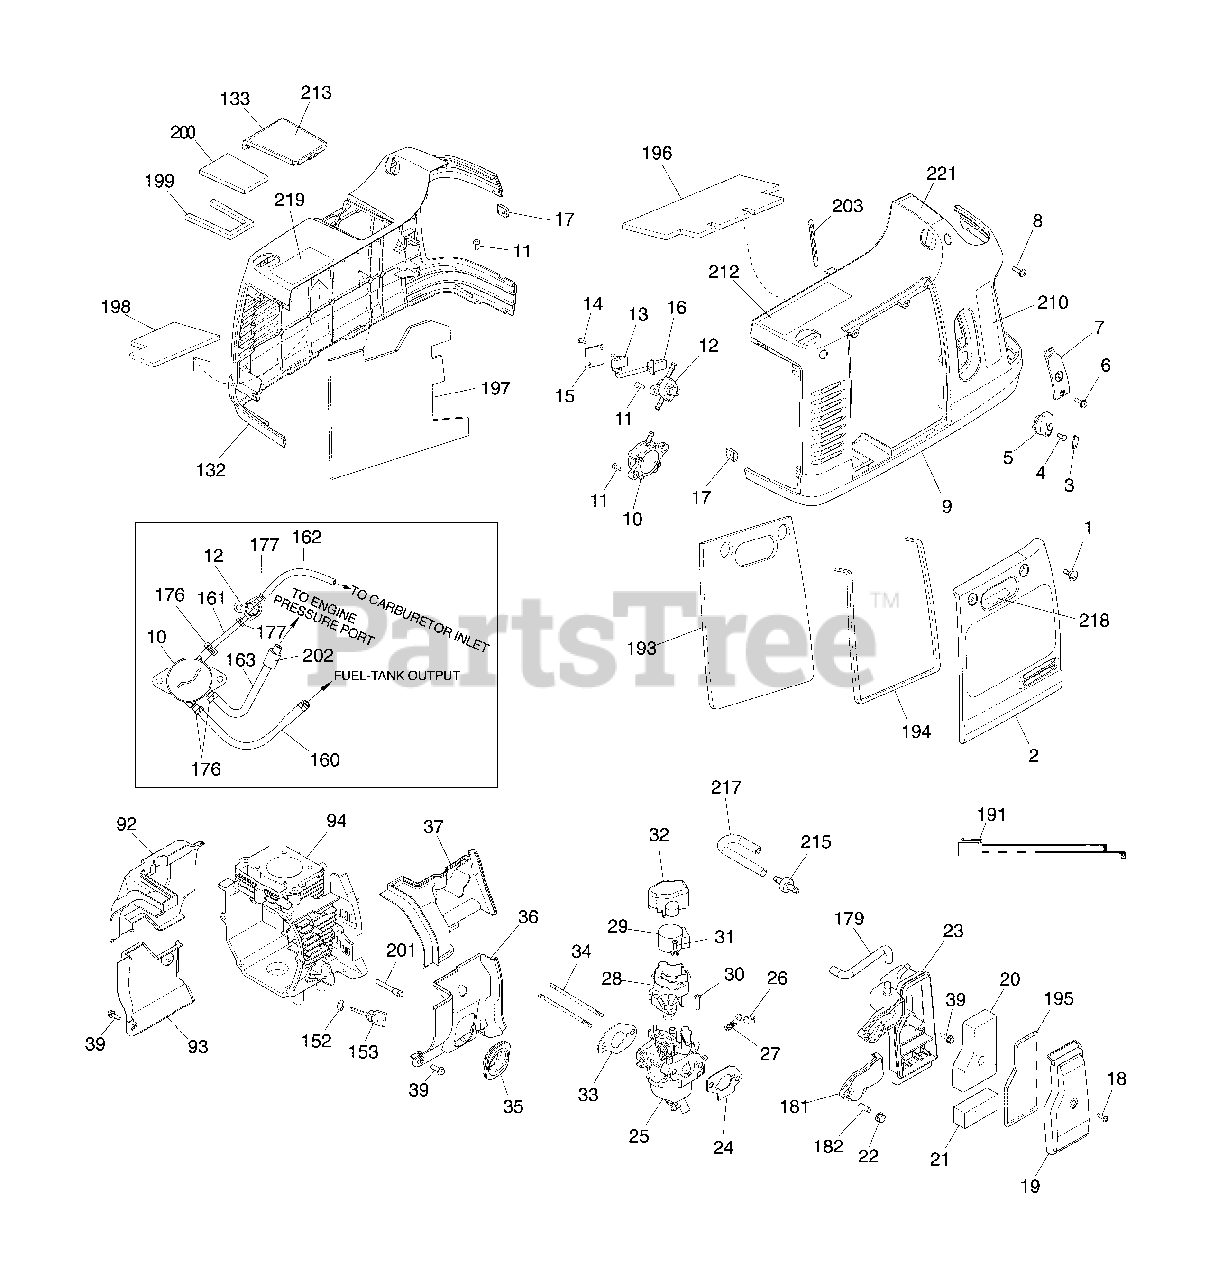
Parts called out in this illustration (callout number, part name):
2	PANEL-ACCESS
4	BOLT
9	COVER-SIDE
11	SCREW
14	BOLT
15	COVER-SWITCH
16	CONNECTION
17	NUT
19	COVER-AIR CLEANER
20	FILTER-A/C FOAM
21	FILTER-A/C FOAM
22	NUT
23	BASE-AIR CLEANER
24	GASKET-AIR CLEANER
27	SPRING
30	BOLT
31	BOLT
35	SEAL-RUBBER
36	DEFLECTOR
37	DEFLECTOR
92	DEFLECTOR
93	DEFLECTOR
94	CRANKCASE
132	COVER-SIDE
133	COVER-SPARK PLUG
176	CLAMP
177	CLAMP
181	COVER-AIR CLEANER
182	SLEEVE
193	FOAM
194	SEAL
195	SEAL
196	FOAM
197	FOAM
198	FOAM
199	SEAL
200	FOAM
201	CYLINDER-BREATHER TUBE
202	TUBE
203	BRACKET
